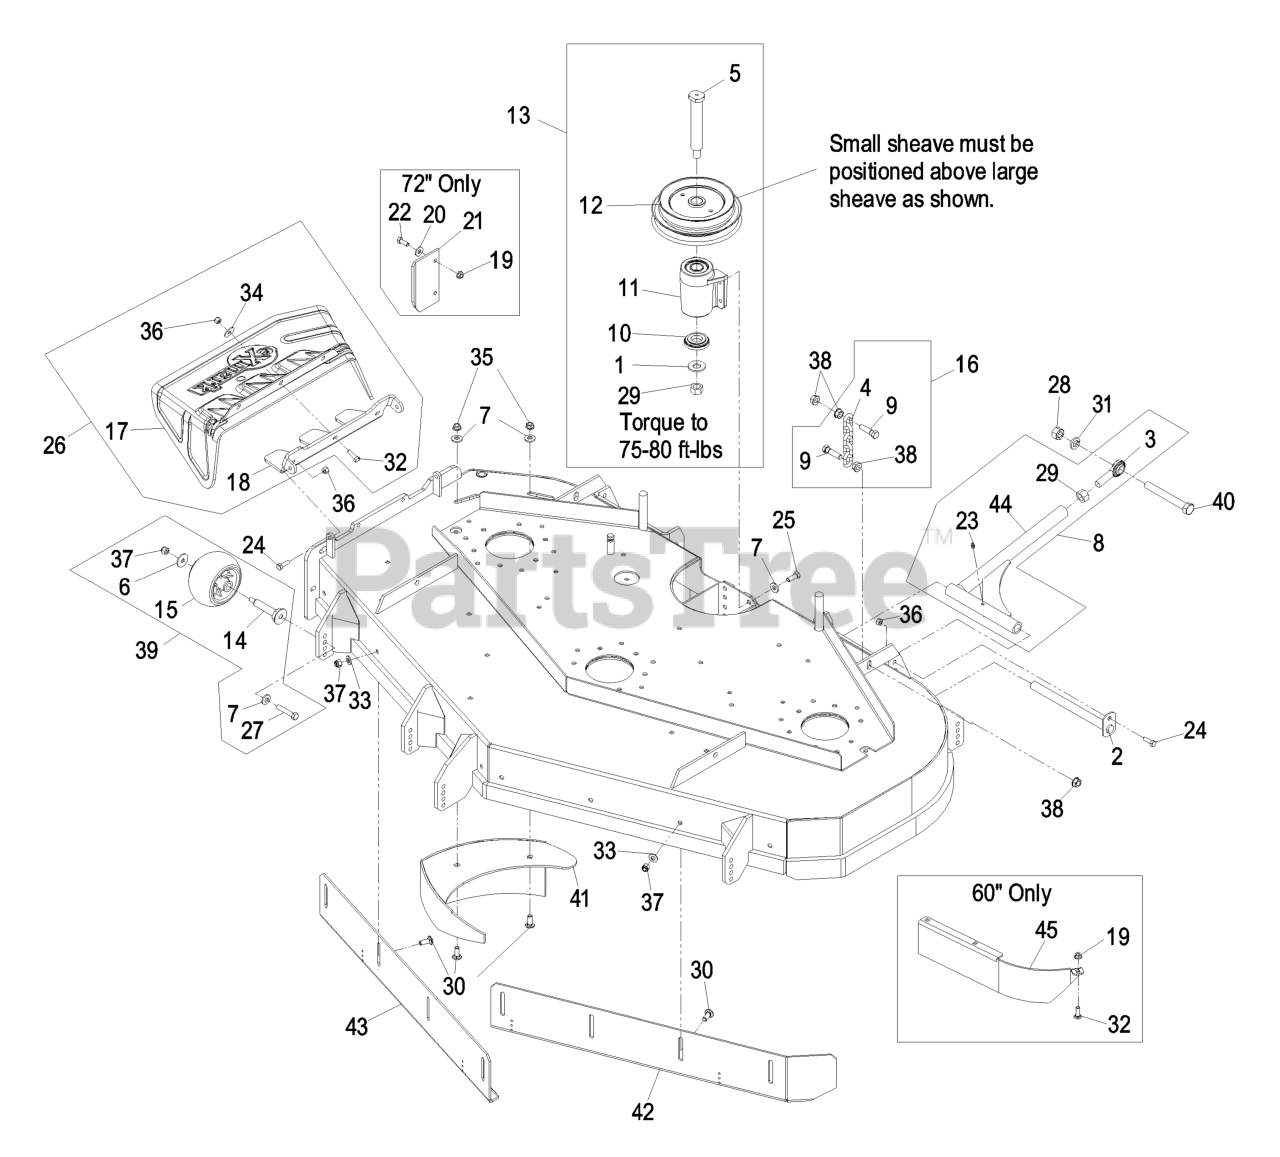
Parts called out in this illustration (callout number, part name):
1	WASHER-SPRING
2	PIN-STRUT
3	BALLJOINT-SPHERICAL
4	CHAIN-LIFT, DECK
5	JACKSHAFT
7	WASHER-BELLEVILLE
8	STRUT ASM
9	SCREW-HH
10	SPACER-GUARD, BOTTOM
11	KIT, JACKSHAFT ASSY
12	SHEAVE, JACKSHAFT DOUBLE
13	KIT,JACKSHAFT 60/72-3750
15	ROLLER-SCALP, ANTI
16	DECK CHAIN ASM
17	CHUTE,DISCHARGE LZ
18	HINGE,DISCHARGE CHUTE
20	WASHER-FLAT
21	DEFLECTOR,DISCHARGE
22	SCREW-HH
23	FITTING-GREASE
24	SCREW-HH
25	SCREW-HH
26	ASM, DISCHARGE CHUTE
27	SCREW-HH
28	NUT-HEX
29	NUT-HEX
30	SCREW-CARR
31	WASHER-LOCK
32	SCREW-CARR
33	WASHER-FLAT
34	WASHER-FLAT
35	NUT-HHF, WHIZ
36	NUT-LOCK, NI
37	NUT-LOCK, NI
40	SCREW-HH
41	WLD,DOGLEG 605
42	WLD,BAFFLE FRT ADJ LH 605
43	WLD,BAFFLE FRT ADJ RH 605
45	BAFFLE,SCROLL 605
